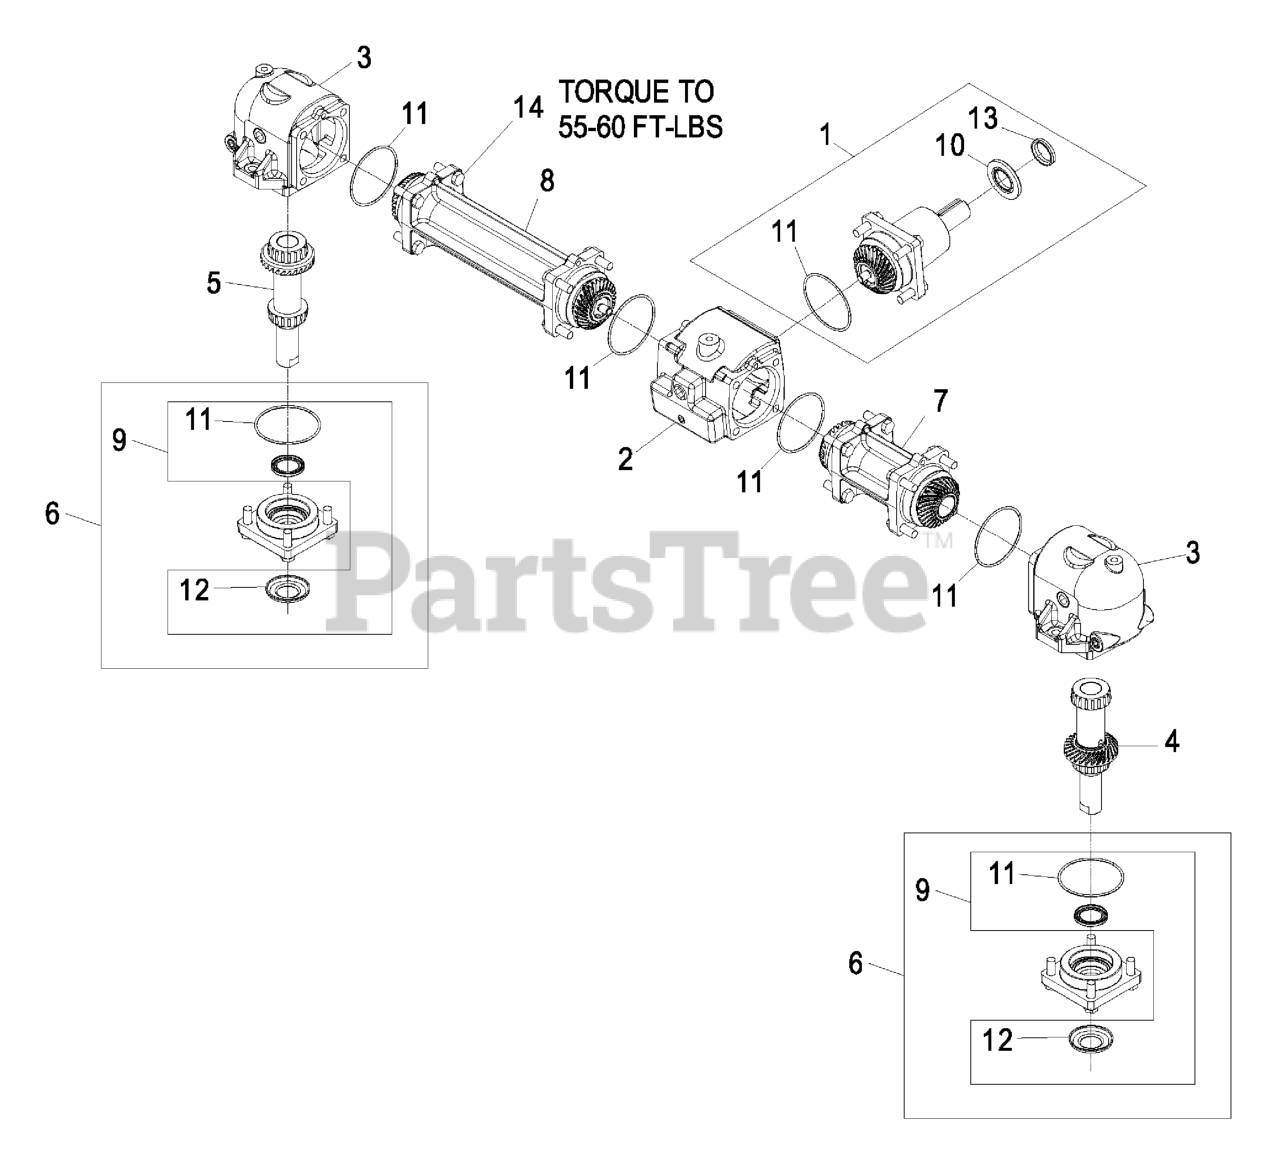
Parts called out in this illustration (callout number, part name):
1	INPUT PINION ASM
2	HOUSING-CENTER
3	HOUSING-END
4	LH OUTPUT SHAFT AND GEAR
5	RH OUTPUT SHAFT AND GEAR
6	CAP-OUTPUT
7	TUBE-CONNECTOR, SHORT
8	TUBE-CONNECTOR, LONG
9	OUTPUT SEAL KIT
10	SEAL-INPUT
11	SEAL-O-RING
12	WASHER-CUPPED
13	SEAL-V-RING
